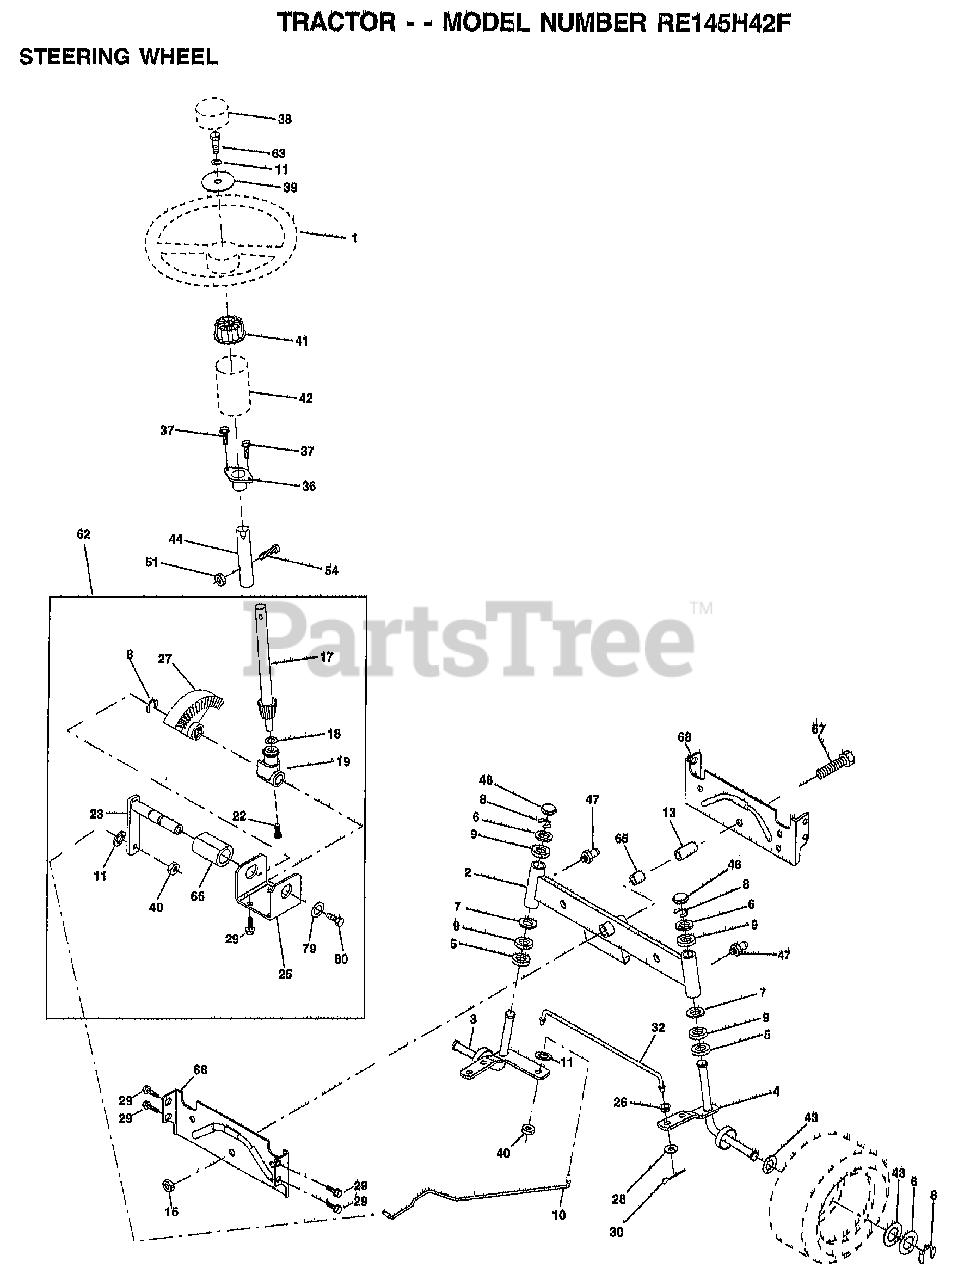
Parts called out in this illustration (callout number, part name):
2	AXLE ASM
3	SPINDLE.ASM.LH
4	"SPINDLE ASM,RH"
5	WASHER .T
6	WASHER
7	WASHER
8	RING
9	COL. SRTG. BEAR.
10	DRAGLINK-STAMPED
11	LOCKWASHER
13	BEARING AXLE
15	"NUT-LOC,FLANGE LT"
17	SHAFT ASM STEERIN
18	THRUST WASHER
19	SUPPORT.SHAFT.STEER
22	SCREW.HX.WSH.HD
23	SHAFT.ASM.PITMAN
25	BRKT-STEERING
26	BUSHING.DRAGLINK
27	GEAR SECTOR
28	WASHER
29	SCREW
32	TIE ROD
36	BUSHING.STEERING
37	"SCREW-TT,10-32 FL"
38	ST WHL INSERT CAP
39	WASHER
40	GRIPCO NUT
41	ADAPTER LT
42	BOOT.STEERING.DASH.P/L
43	WASHER
44	EXT SHAFT STEERIN
46	CAP
47	ZERK M
51	NUT
54	BOLT
62	KIT.STEER.ASM
63	BOLT
65	SPACER AXLE
66	"BEARING-ARM,PITMA"
67	BOLT
68	BRACE AXLE
79	WASHER
80	BOLT.HX.NYLON3/8-16X3/
